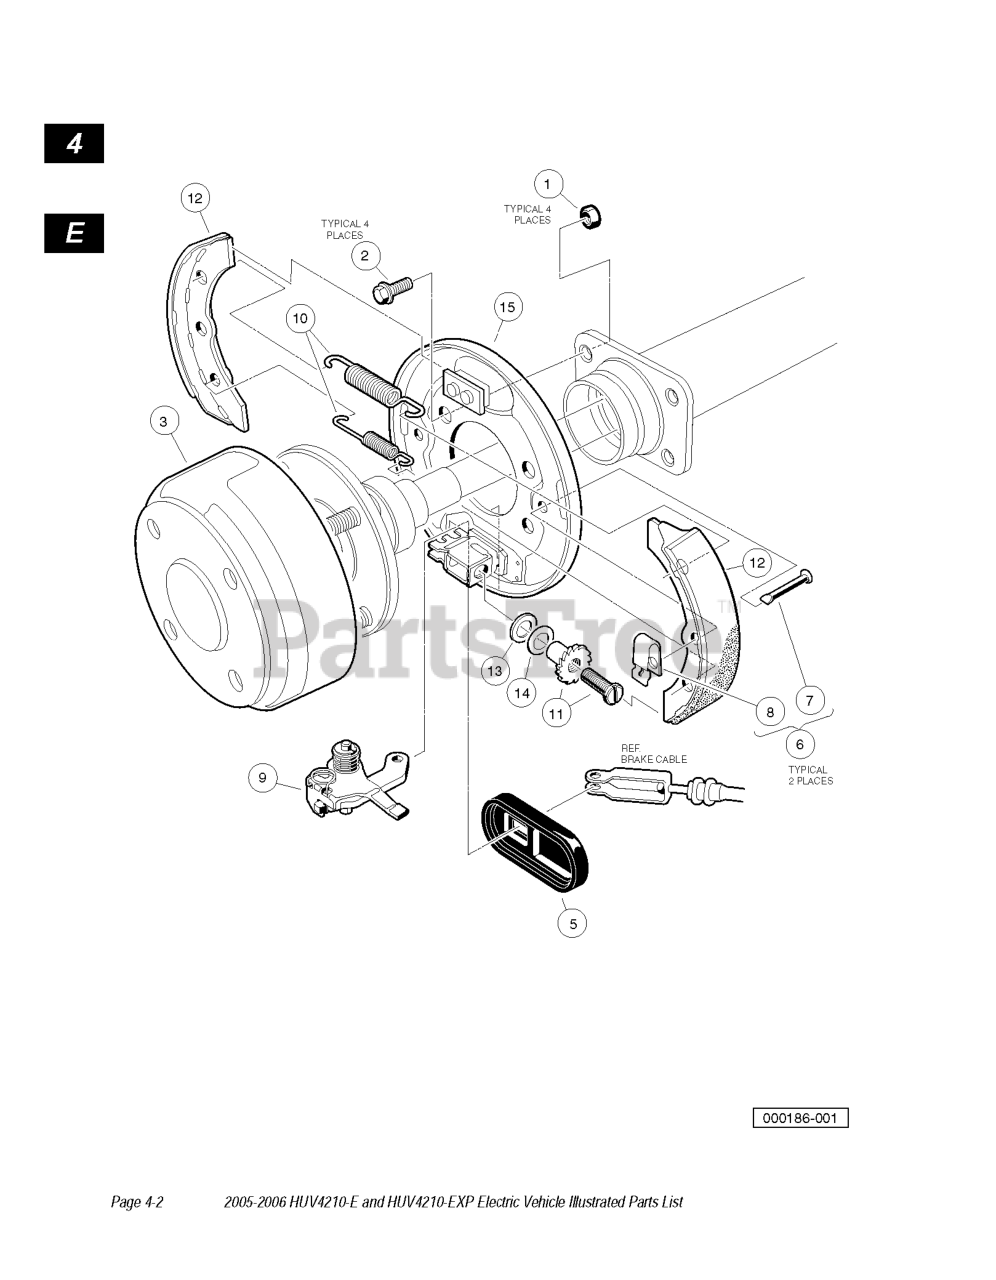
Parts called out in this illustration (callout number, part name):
2	BOLT, BRAKE CLUSTER MOUNTING
3	DRUM W/O CENTER HOLE, BRAKE
4	CLUSTER ASSY, RH BRAKE
5	DUST COVER
6	KIT, SHOE RETAINER
9	LEVER ASM S.A. BRAKE RH
10	PACKAGE BRAKE SPRING SELF ADJ
11	ADJ MECHANISM S.A. BRAKES RH
12	BRAKE SHOE PACKAGE SELF ADJ
13	PLATE WASHER BRAKE SELF ADJ
14	WASHER BRAKE SELF ADJ
15	PLATE ASSY, RH BRAKE BACKING
16	CLUSTER ASSY, LH BRAKE
17	DUST COVER
18	KIT, SHOE RETAINER
21	LEVER ASM S.A. BRAKE LH
22	PACKAGE BRAKE SPRING SELF ADJ
23	ADJ MECHANISM S.A. LH
24	BRAKE SHOE PACKAGE SELF ADJ
25	PLATE WASHER BRAKE SELF ADJ
26	WASHER BRAKE SELF ADJ
27	PLATE ASSY, LH BRAKE BACKING
